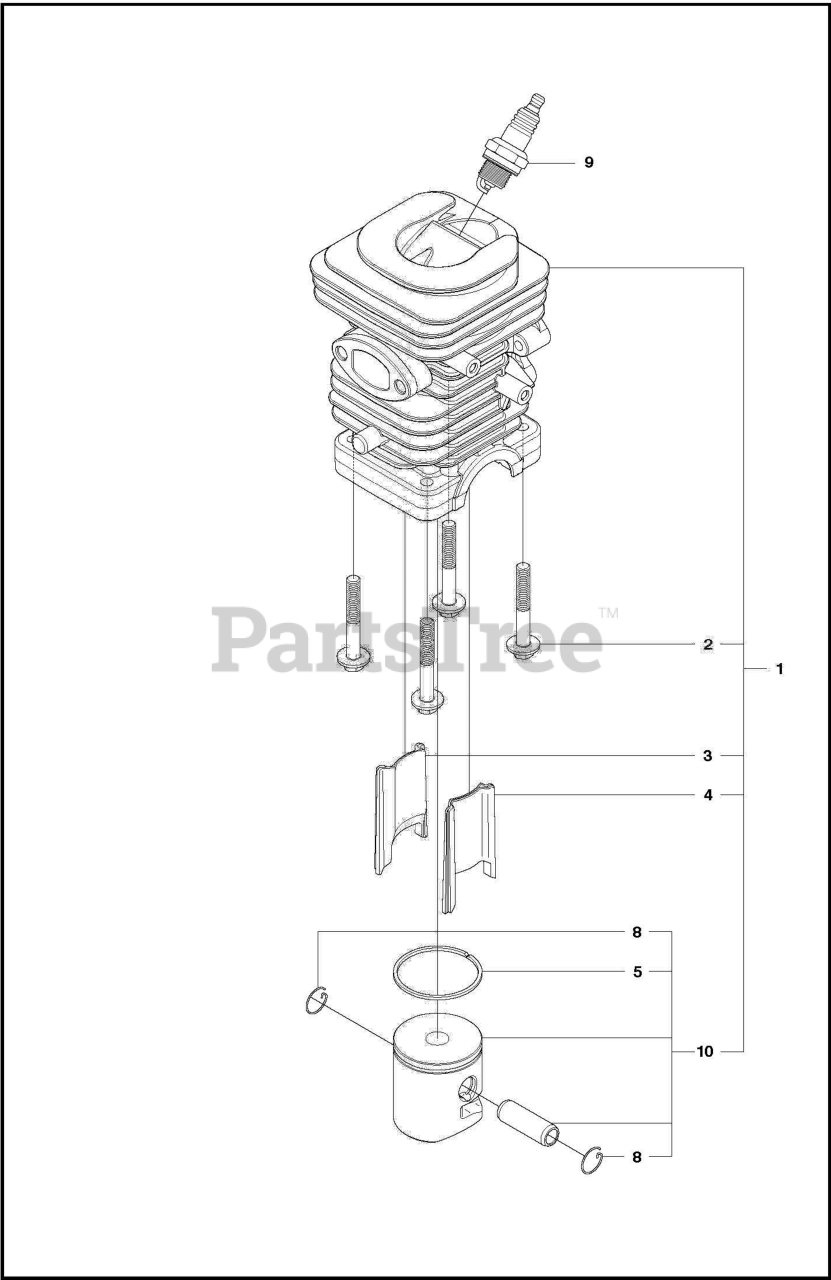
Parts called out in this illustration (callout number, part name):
1	Pistons
1	KIT PISTON AND CYLINDER
2	BOLT
3	CYLINDER INSERT LEFT 38CC
4	CYLINDER INSERT RIGHT 38CC
5	PISTON RING 38CC
5	PISTON RING
8	C-CLIP,PSTN PIN 36/41
9	SPARK PLUG RCJ7Y
10	PISTON KIT
10	KIT PISTON HARDMOUNT BEARING
